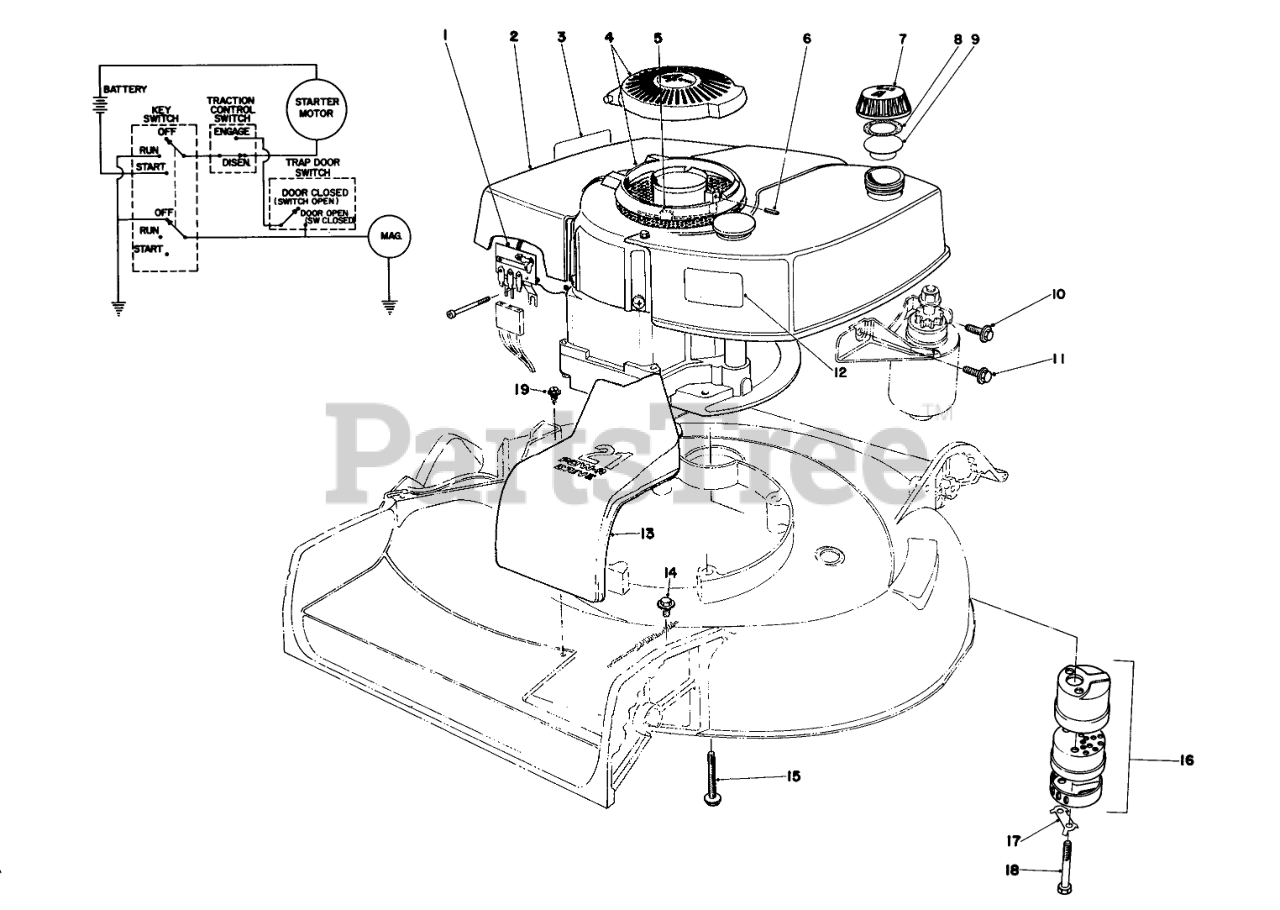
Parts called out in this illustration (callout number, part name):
1	SWITCH & TERM BLK CVR
2	Engine
3	Decal-Maintenan
4	Cover Assembly
5	WIRE CLIP
6	SPRING PIN
7	Gas Cap (Incl. Ref. #8 & 9)
8	GASKET
9	GAS CAP BAFFLE
10	SCREW
11	Screw
12	High Torque
13	Cover Belt Drive
14	SCREW-HWHTF
15	3/8-16 X 2-3/4 CAPSCR
16	Muffler Assy. (Incl. Ref. #17 & 18)
17	CLIP - LOCKING
18	SCREW-HH
19	SCREW
